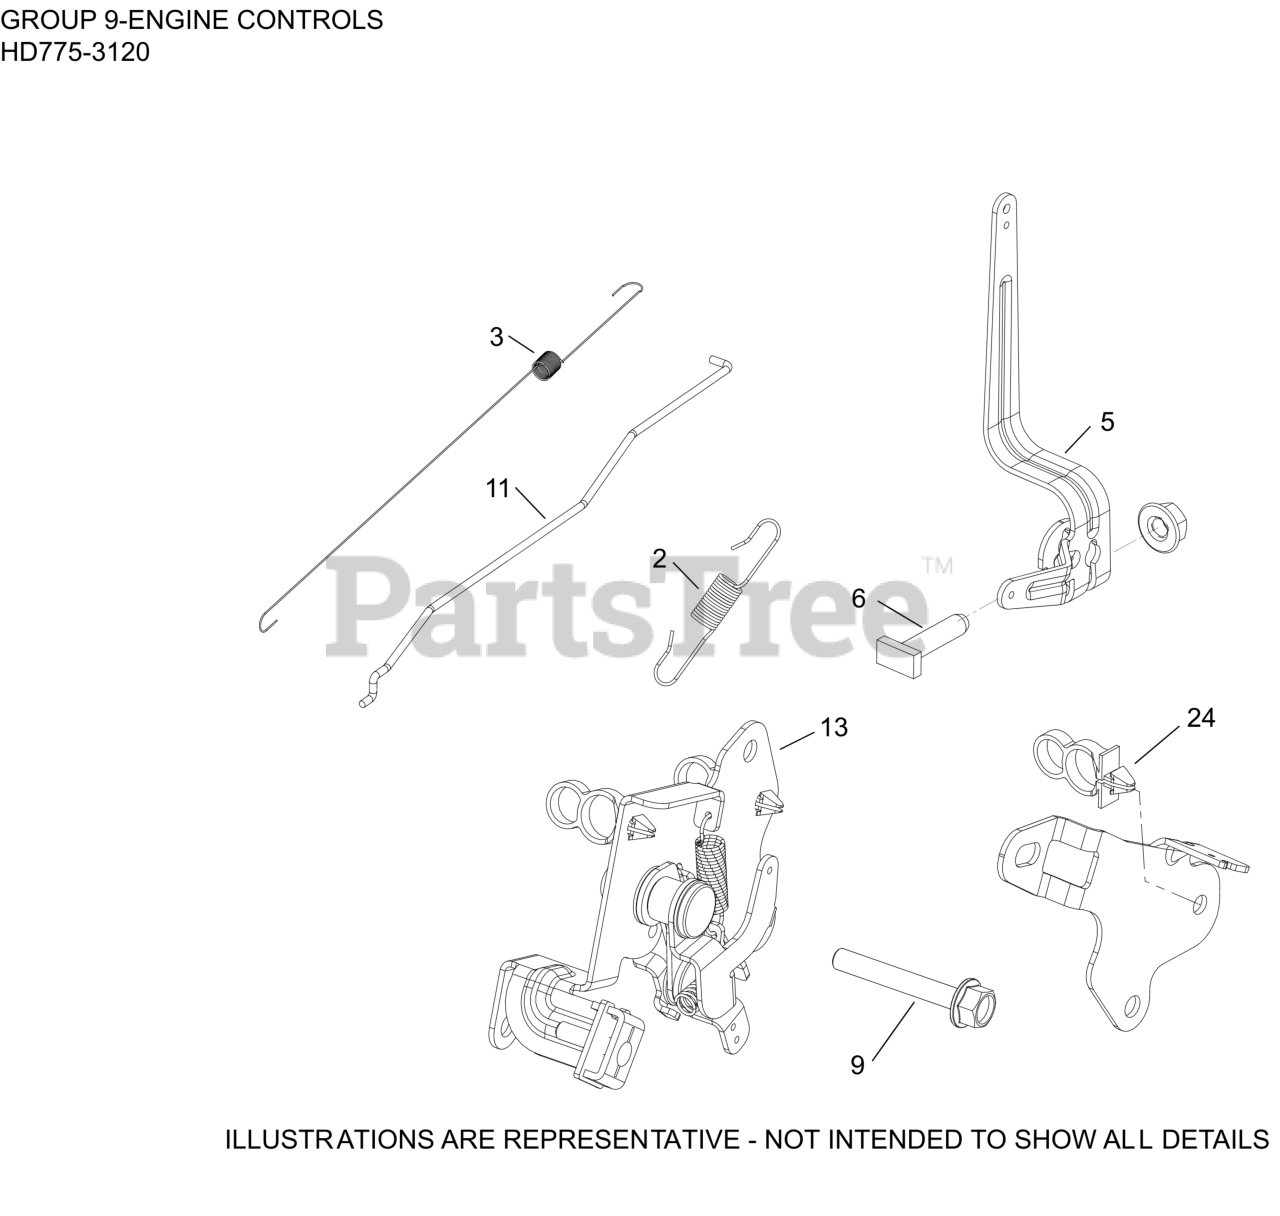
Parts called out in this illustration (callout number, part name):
2	SPRING, EXTENSION (GOVERNOR)
3	SPRING, LINKAGE
5	LEVER, GOVERNOR
6	SCREW, RECTANGLE HEAD (M6)
9	SCREW, HEX FLANGE (M6)
11	LINKAGE, GOVERNOR
13	CONTROL ASSY, REMOTE VARIABLE SPEED
24	CLIP, FUEL LINE
